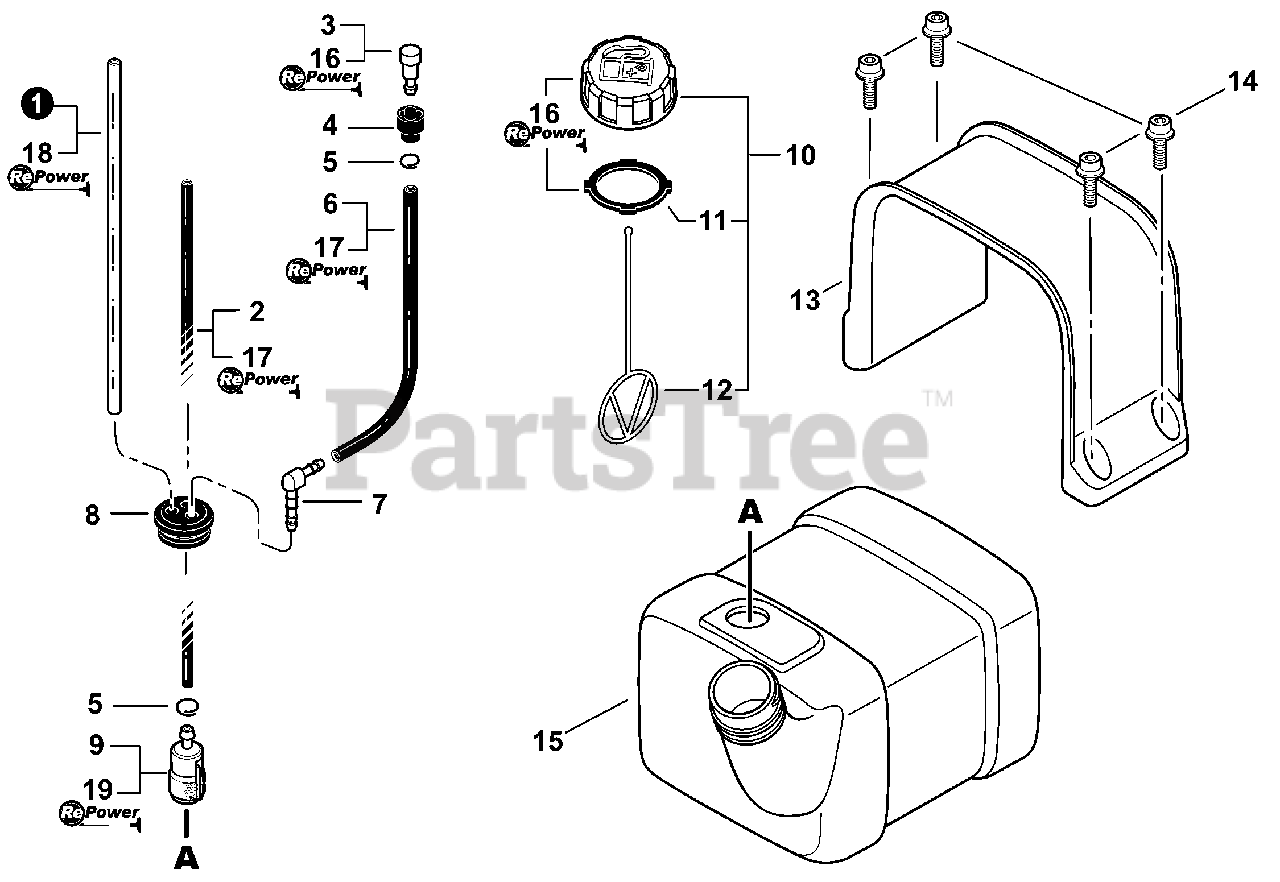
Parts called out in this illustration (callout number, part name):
1	PIPE, FUEL RETURN 3×6×145
2	PIPE, FUEL 3×6×230
3	VENT ASSY
4	HOLDER, VENT
5	CLIP 6.5MM
6	PIPE, VENT 3×6×145mm
7	CONNECTOR, PIPE 5.4
8	GROMMET, FUEL
9	FILTER, FUEL
10	CAP ASSY, FUEL
11	GASKET, FUEL CAP
12	CONNECTOR, CAP L= 100mm
13	BRACKET, FUEL TANK
14	BOLT 5×16
15	TANK, FUEL
16	CAP/VENT KIT - REPOWER
17	PIPE, BULK - REPOWER 3×6mm BLACK
18	PIPE, BULK - REPOWER 3×6mm CLEAR
19	TUNE-UP KIT - REPOWER
